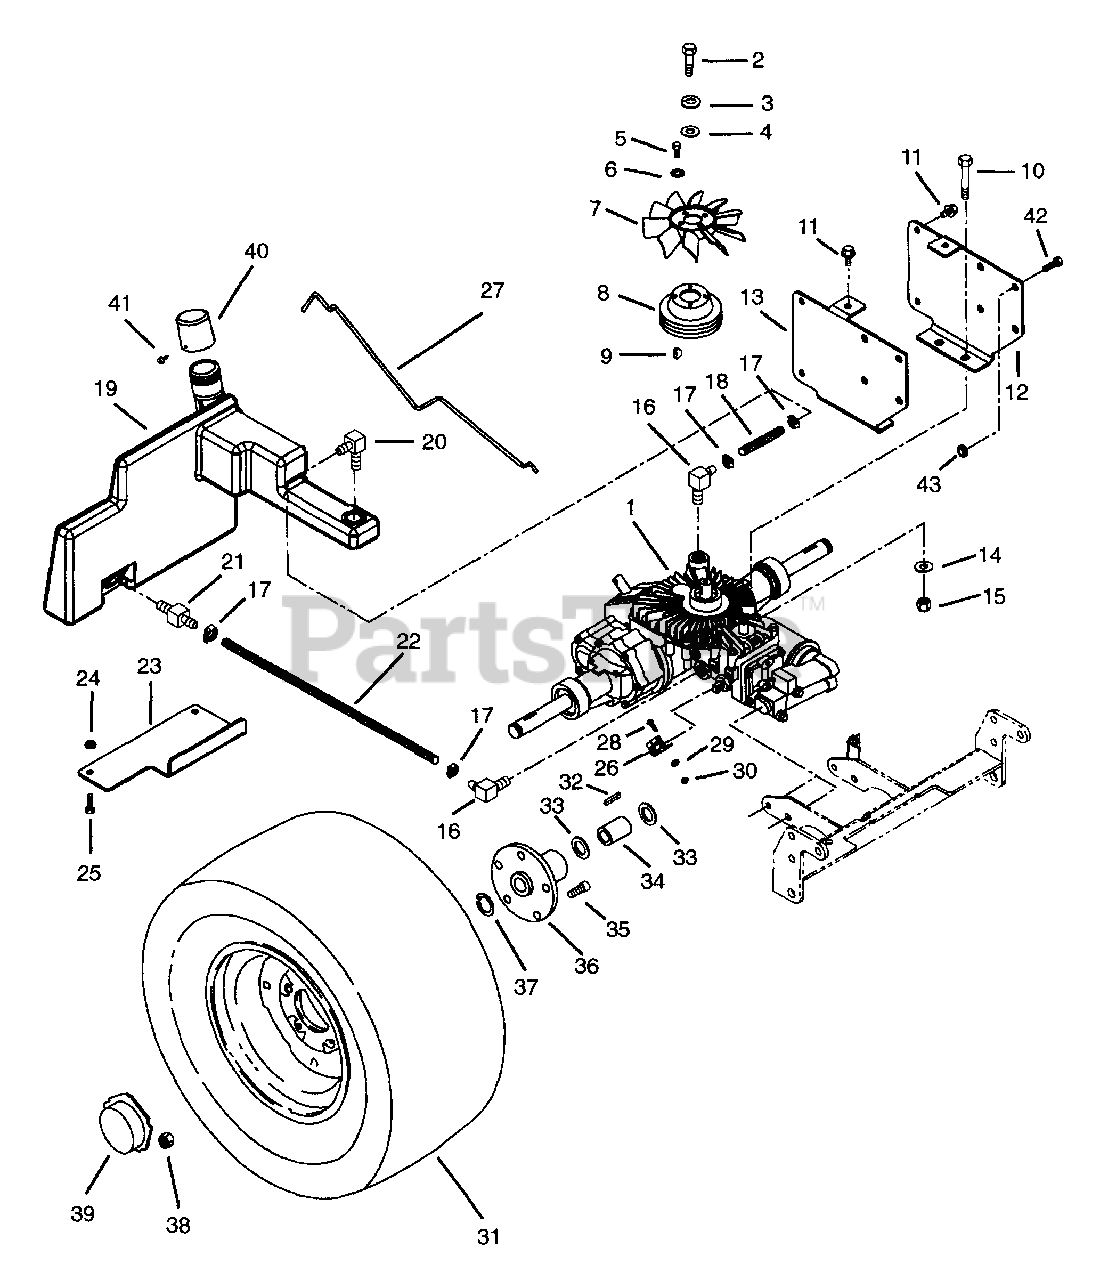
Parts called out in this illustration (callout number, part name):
1	TRANSAXLE - HYDRO
2	BLT-HEX .25-20X1.00 PL GR5
3	WSHR-LK .250X.077 HVY PL
4	WSHR-FL-STL .265X1.370X.145
5	BLT-HEX 10-24X.38 PL GR2
6	WSHR-LK-EXT #10 ID X .022
8	SHEAVE - TRANSAXLE
9	KEY-WDRF .188X.625X.25 SAE 61
10	BLT-HEX .38-16X3.00 PL GR5
11	SCR-TAP .375-16X .50 HWH PL TR
12	MOUNT, AXLE L.H.
13	MOUNT, AXLE R.H.
14	WSHR-FL-STL.406X.812X.065PL
15	NUT-LK-NYL .375-16 PL
16	FITTING
17	CLAMP-HOSE WRM .38/.62X.50 #10
18	HOSE, .625 ID X.906 OD X 6.50
19	RESERVOIR, OIL
20	ELBOW, BARBED .625
21	ADPTR-MALE
22	HOSE, .625 ID X.906 OD X 10.75
23	BRACE, OIL RESERVOIR
24	NUT-LK-NYL.312-18 PL
25	BLT-HEX .31-18X.75 PL GR5
26	ARM, DUMP VALVE
27	ROD, DUMP VALVE
28	BLT-HEX .25-20X1.00 PL GR5
29	WSHR-LK .250X.077 HVY PL
30	NUT-HEX .250-20 PL
31	T/WHL ASSY 10.50X23
32	KEY-STR .25X2.0X.25
33	WSHR-FL-STL 1.010X1.505X.062PL
34	SPACER 1.006X1.437X1.928
35	BLT-LUG SERNKHDND .44-20X1.188
36	WHEEL HUB
37	RG-RTNG-EXT 1.00X.078
38	NUT-LUG .437-20 YWZC
39	REAR HUB CAP
40	CAP - OIL RESERVOIR
41	SCR-DR 8-18X.50
42	BLT-HEX .38-16X1.00 PL GR5
43	NUT-LK TOP .375-16 GR C YWZC
